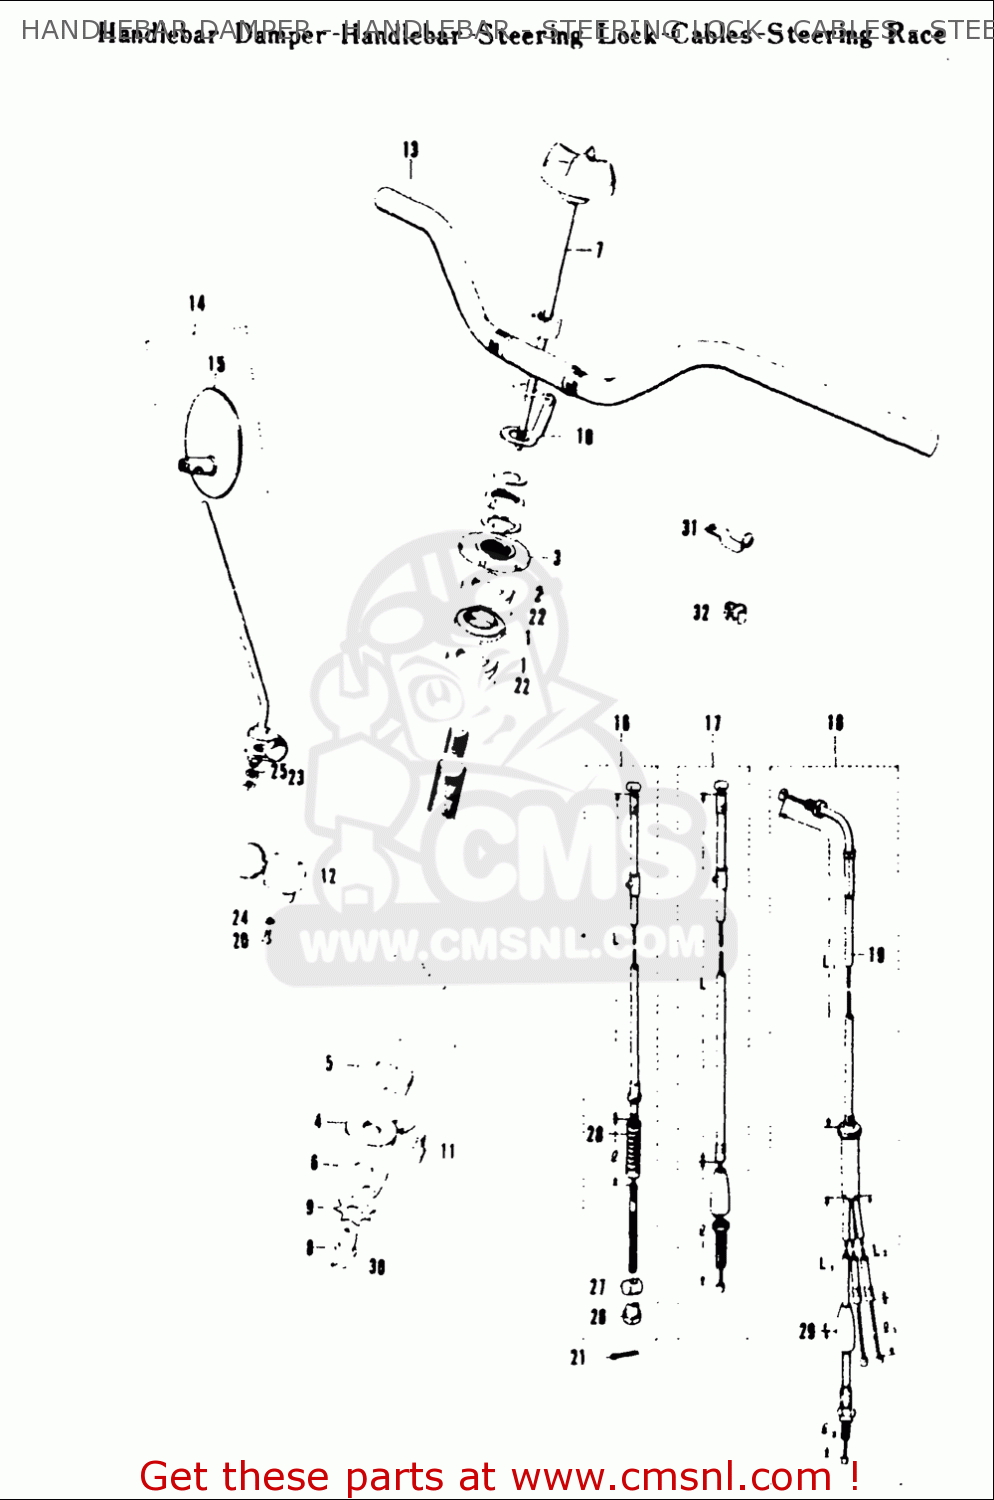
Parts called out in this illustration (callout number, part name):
3	NUT,STEERING STEM
6	SPACER,STEERING DAMPER
8	HUB,HANDLEBAR DAMPER S
9	SPRING, DAMPER ADJUST
10	STOPPER, DAMPER KNOB
11	BRACKET,STEERING DAMPER
20	SCREW
22	BALL
23	NUT
24	WASHER,LOCK
25	WASHER
26	NUT
27	PIN(13X18)
28	SEAL,DUST
30	CLIP
32	CLIP
